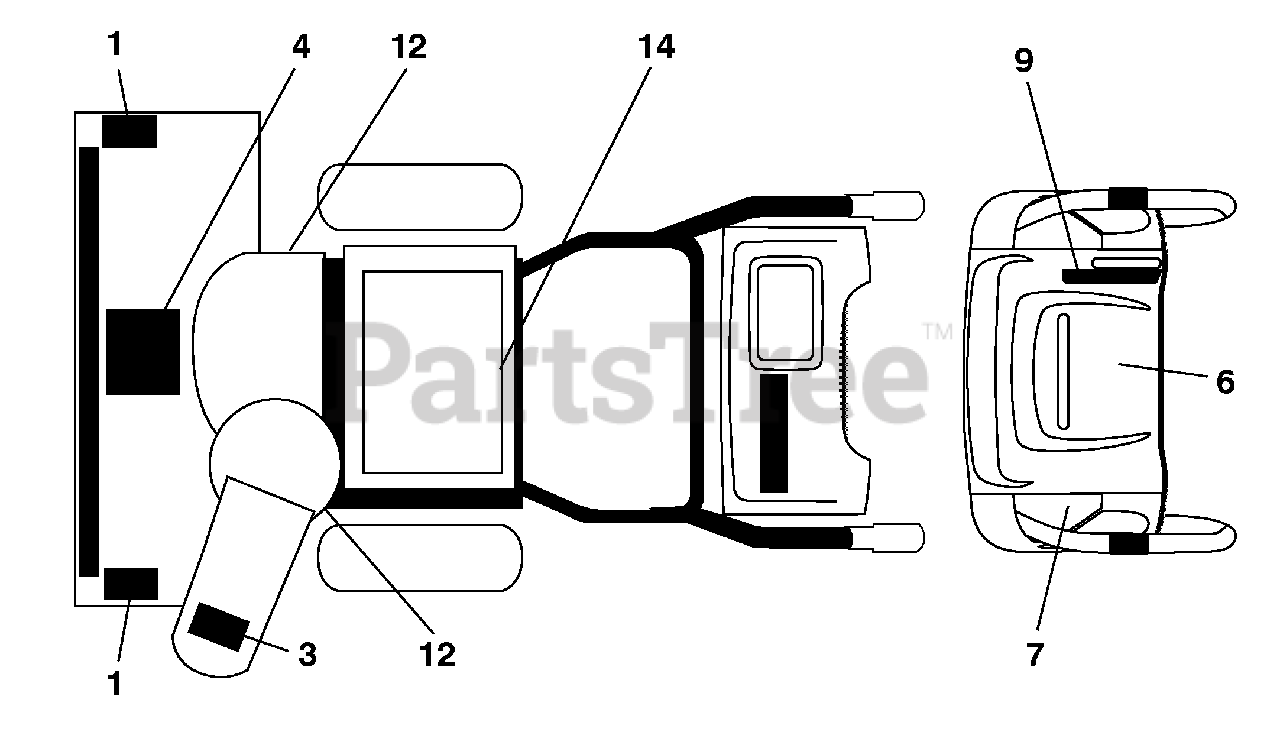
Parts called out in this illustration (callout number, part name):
1	DECAL, DANGER
3	DECAL, DANGER, DEFLECTOR
4	DECAL, DANGER
6	DECAL, INSTRUCTION
7	DECAL, TRACTION LEVER
9	DECAL, SPEED CONTROL
12	DECAL, BELT GUARD
14	DECAL, SOUND LEVEL
